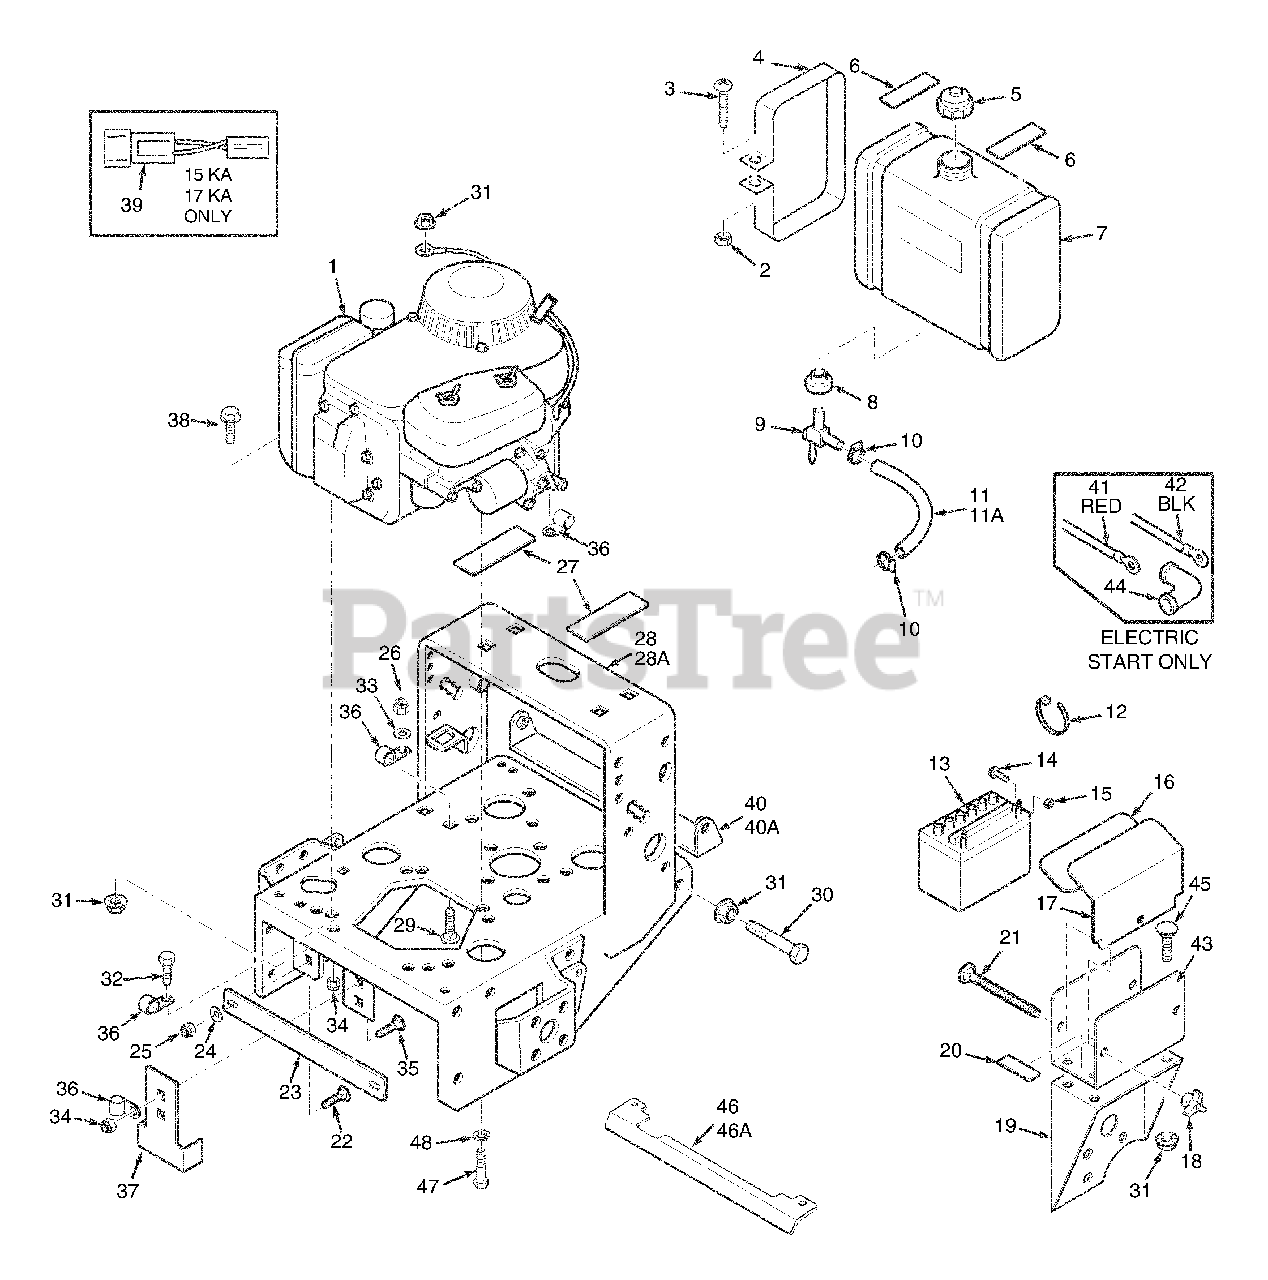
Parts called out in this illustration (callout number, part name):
1	Engine 18KH Kohler
2	Hex Nut, 1/4-20
3	Screw, 1/4-20 x 2" Rnd. Hd. Phil.
4	Strap, Fuel Tank
5	Cap, Fuel Tank
6	Pad, Rubber-Fuel Tank - Upper
7	Fuel Tank Assy.
8	Bushing
9	Valve, Fuel Shut-off
10	Clamp, Fuel Hose
11A	Fuel Hose, 1/4 ID x 10" KH
12	Cable Tie
22	Bolt, Carriage, 3/8-16 X 1-1/4"
23	Brace, 16"
24	Flat Washer .391 x .938 x .105
25	Nut, 3/8-16 Elastic Stop
26	Nut, 1/4-20 Elastic Stop
27	Pad, Rubber-Fuel Tank Lower
28	Engine Deck, 16" Wide, w/decals
29	Bolt, Carriage, 1/4-20 x 1-1/4"
30	Bolt, 5/16-18 x 2" Hex Head
31	Nut, 5/16-18 Serr. Flange
32	Hex Head Bolt, 5/16-18 x 3/4"
33	Flat Washer 1/4"
34	Nut, 5/16-18 Elastic Stop
35	Bolt, Carriage, 5/16-18 x 1"
37	Clutch Bracket
40	Pulley Guard, 16" Frame
46	Heatshield (16" Small Frame)
47	Bolt, 5/16-18 x 1" Serrated Flange Hex Head
48	Lock Washer 5/16"
